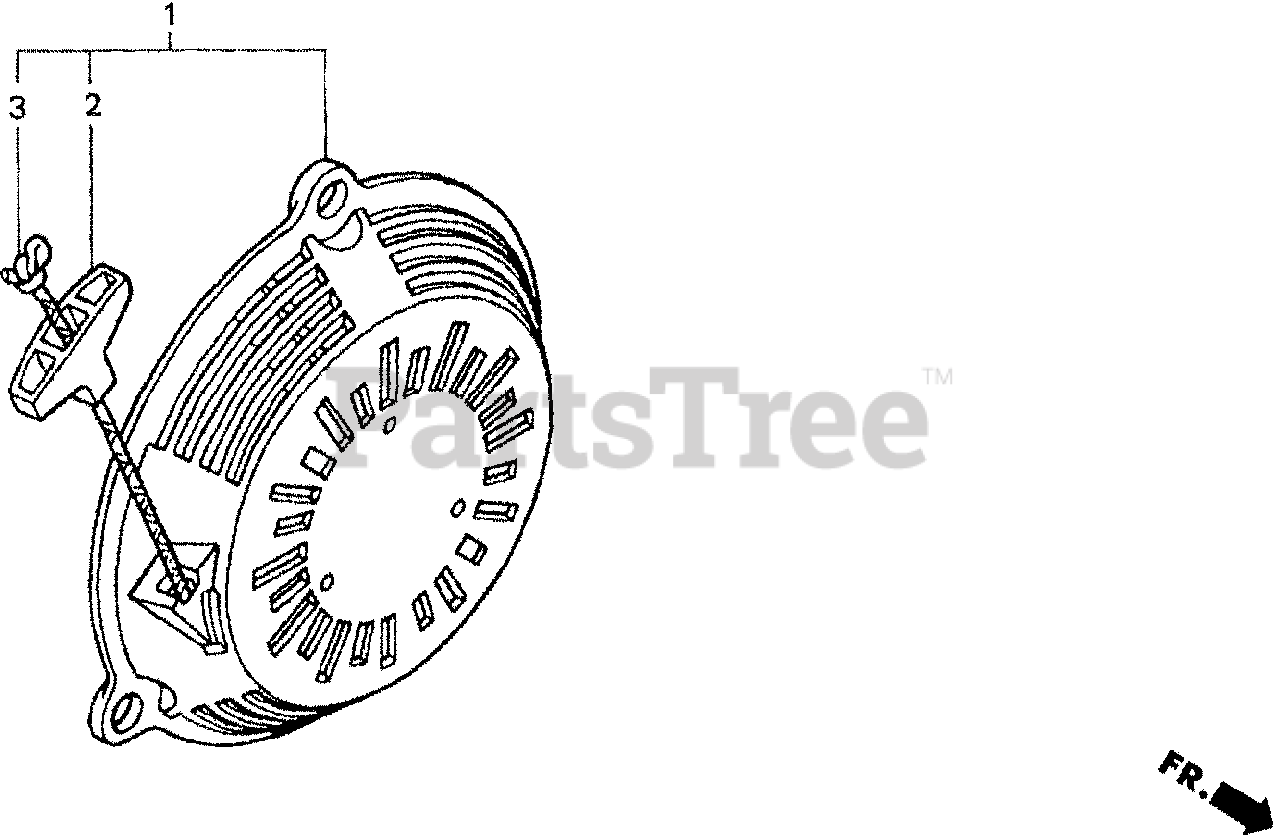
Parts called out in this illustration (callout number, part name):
1	STARTER ASSY., RECOIL *R280* (POWER RED)
2	KNOB, RECOIL STARTER
3	ROPE, RECOIL STARTER (#3.5X52")
